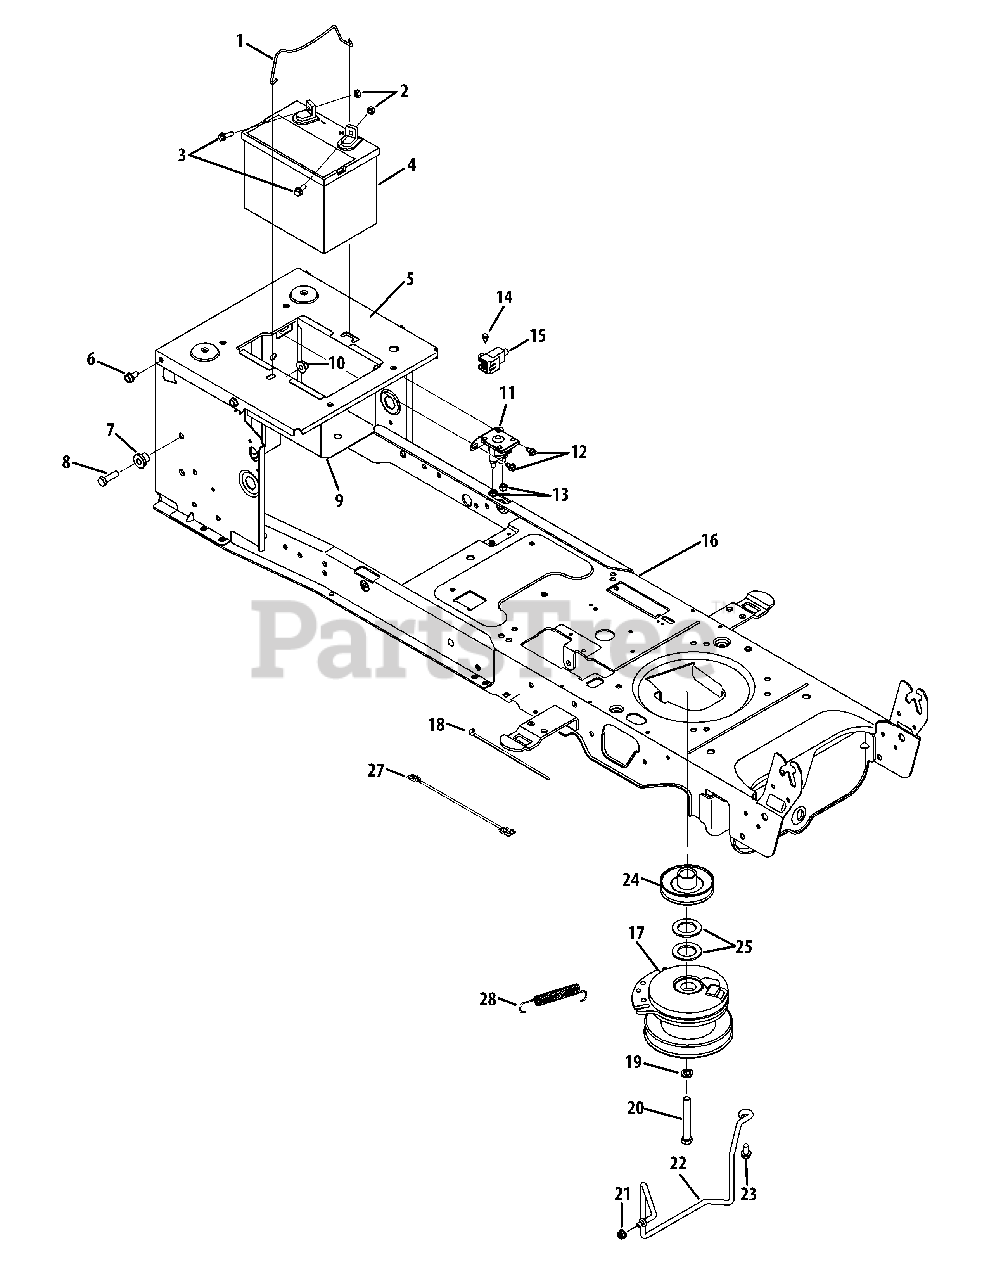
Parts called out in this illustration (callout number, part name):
1	Battery Hold Down Rod
2	Sems Hex Nut 1/4-20
3	Hex Hd. Flg. Scr. 1/4-20 x .75 Gr. 5
4	Battery
5	Seat Frame Bracket
6	Hex Wash Hd. Tapp Scr. 5/16-18 x .75
7	Shoulder Spacer .38 x 1.0 x .70
8	Hex Bolt 3/8-16 x 1.25
9	Battery Tray
10	Flange Lock-Nut 3/8-16 Gr. F Ny lon
11	Solenoid
12	Hex Wash HD Tapp Scr 1/4-20 x .375
13	Hex L-Flanged Nut 1/4-20 Gr. F Nylon
14	Shoulder Screw #10-32 x .50
15	Switch, Interlock
16	Lower Frame Ass’y
17	Electric PTO Clutch (42")
17	Electric PTO Clutch (46")
18	Cable Tie
19	Flat Washer .450 x 1.25 x .164
20	Hex Screw 7/16-20 x 3.5 Gr. 5
21	Flange Locknut 5/16-18 Gr. F, Nylon
22	Keeper Rod (42" & 46")
23	Hex Wash Hd. Tapp Scr. 5/16-18 x .75
24	Engine Pulley
25	Flat Washer 1.03 ID x 1.64 OD x .095
26	Ext. Spring .38 OD x 3.25" Lg.
27	Jumper Clutch Harness (46")
28	Extension Spring
